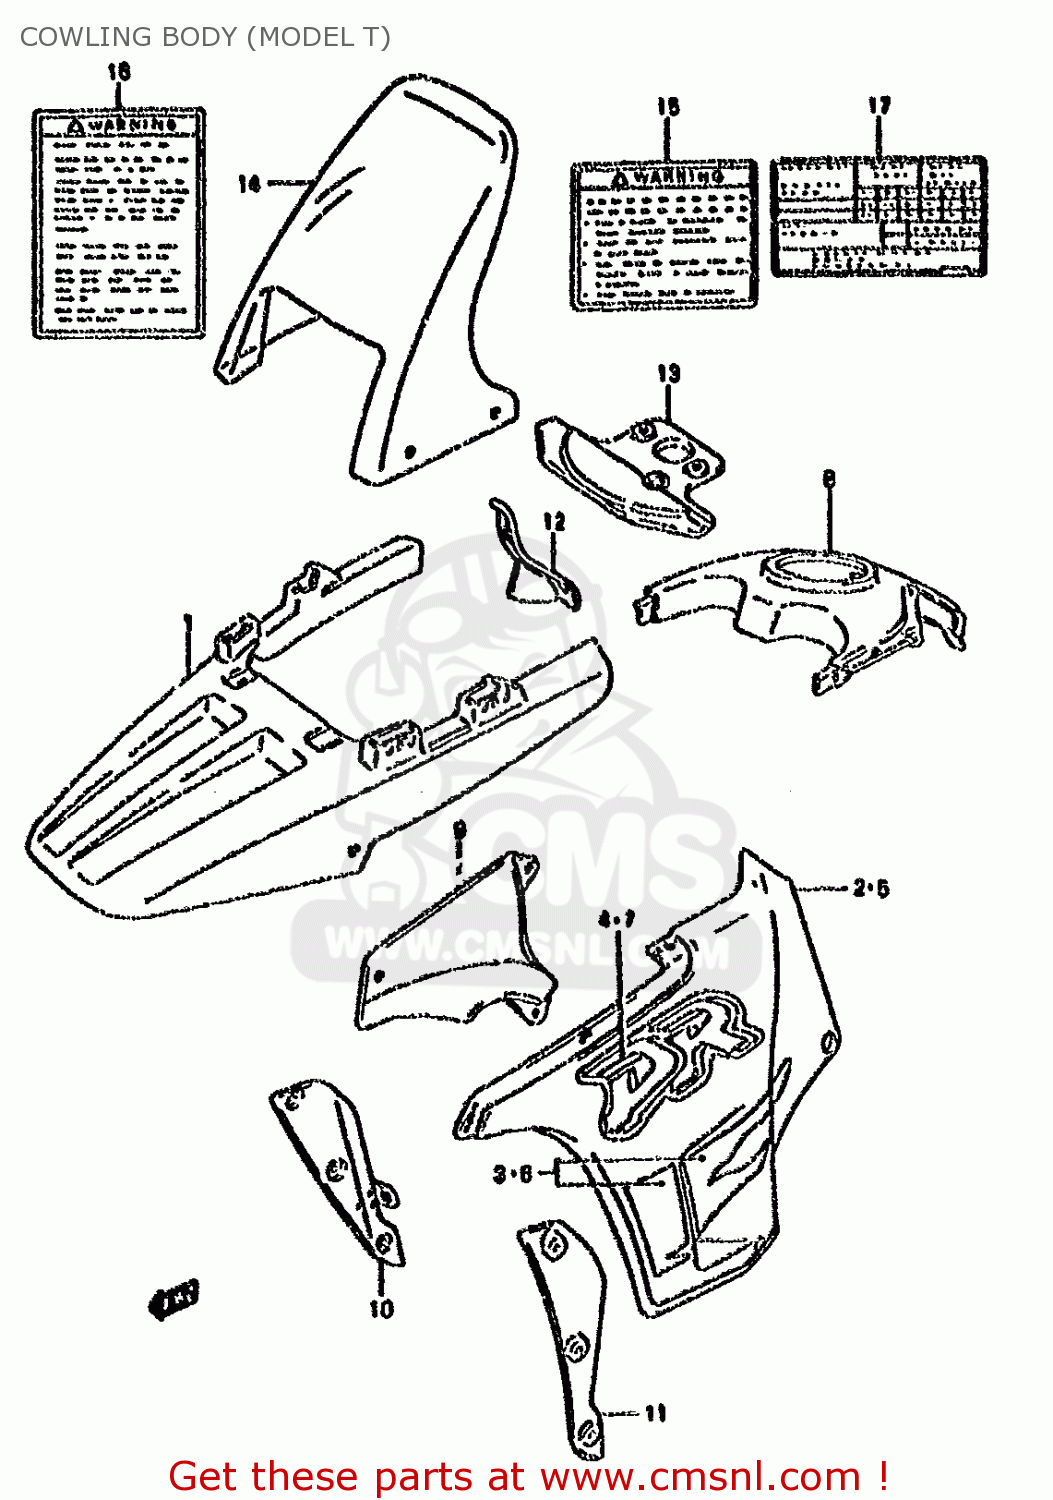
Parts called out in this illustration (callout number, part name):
1	COWLING ASSY,FR
2	COWLING ASSY,SIDE RH (BLACK)
3	TAPE SET,COWL SIDE,R
4	EMBLEM,COWLING SIDE
5	COWLING ASSY,SIDE,L
6	TAPE SET,COWL SIDE,L
7	EMBLEM,COWLING SIDE
8	COWL ,UPPER
9	PANEL,COWLING,INNER,R
10	COWLING, SIDE FRONT RH
11	COWLING,SIDE FR,L
12	PANEL,COWLING,R
13	COVER COWLING,FRONT LOWER
14	WINDSCREEN
15	LABEL,WARNING
16	LABEL (WARNING SCREEN)
17	LABEL, TIRE AIR PRESSURE
21	LABEL, TIRE AIR PRESSURE
22	MANUAL,OWNER'S
23	LABEL (WARNING SCREEN)
24	O.M. DR800S P
25	O.M. DR800S N
